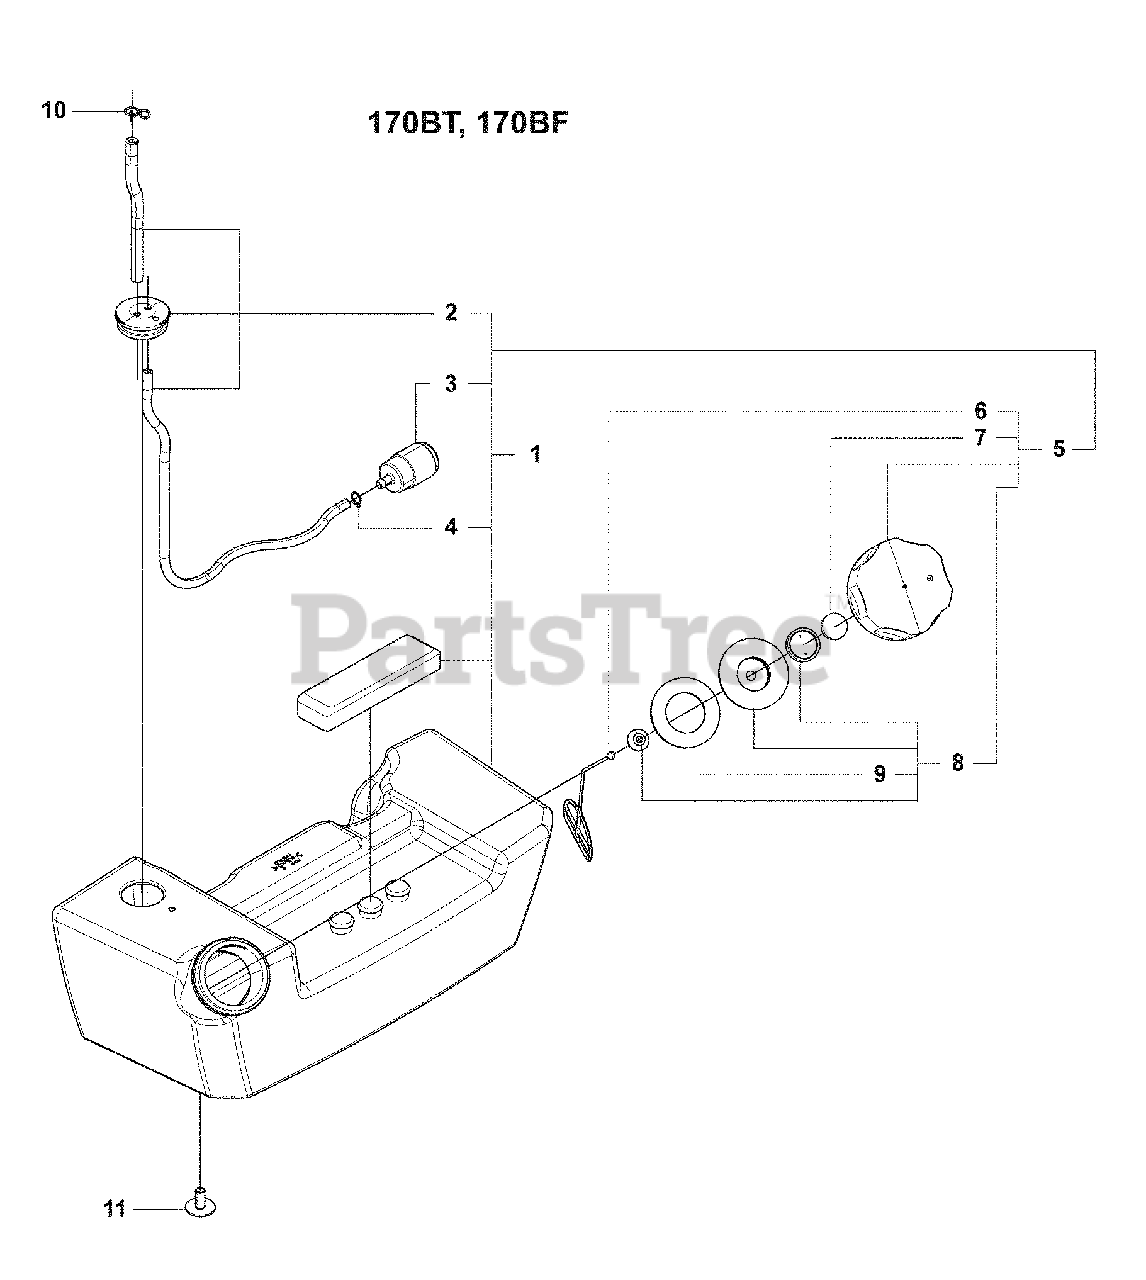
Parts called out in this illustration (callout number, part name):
1A	TANK-A
1B	TANK
2	Pipe, Complete
3	Fuel Filter Assembly
4	Clip
5	Cap, A
6	Stopper
7	Air Filter
8	Holder, A
9	Packing
10	Clip
